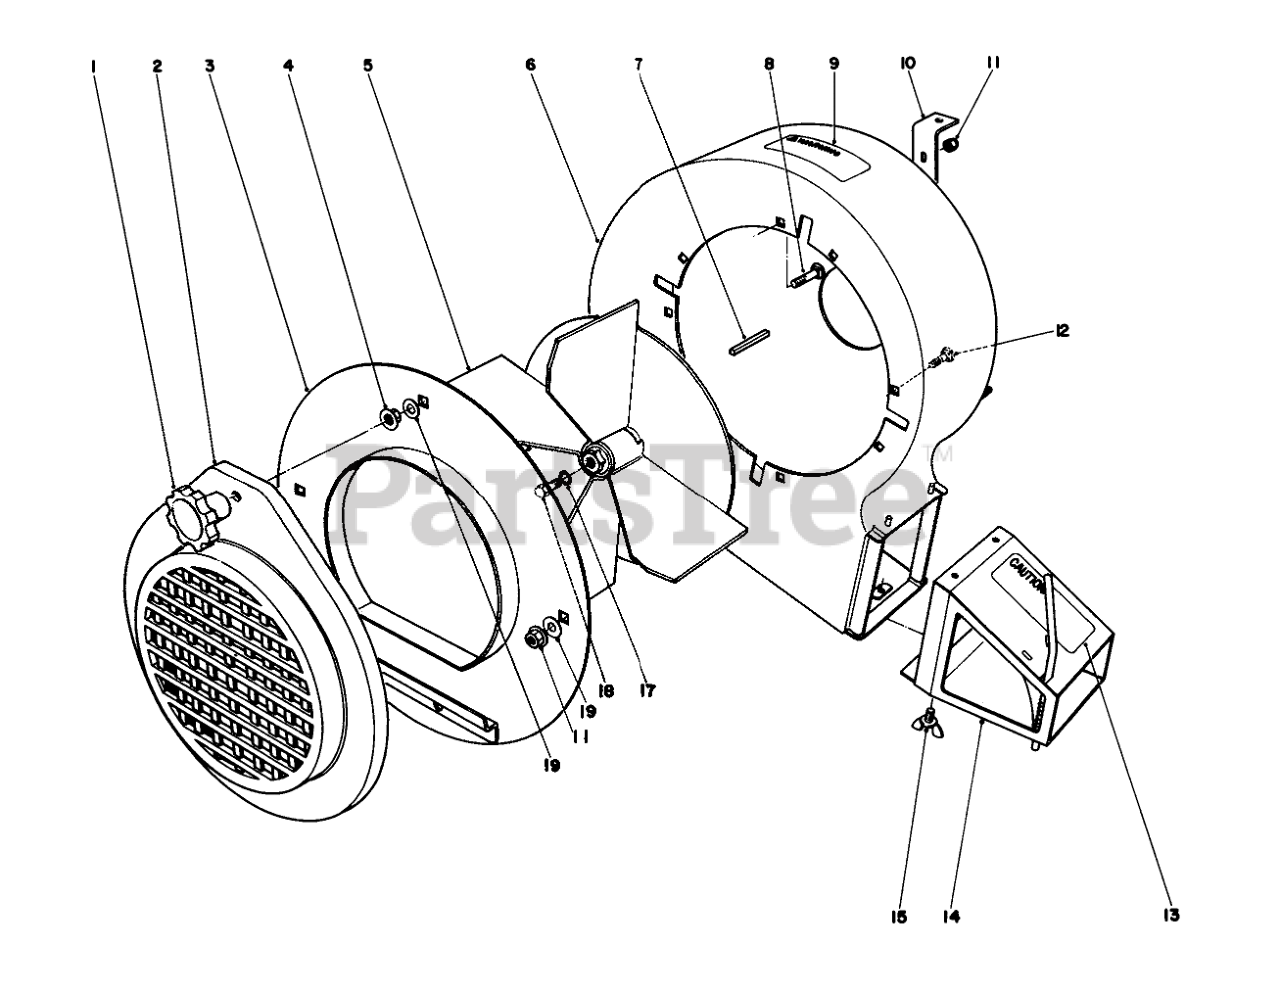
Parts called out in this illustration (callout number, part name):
2	INTAKE-BLOWER
3	Blower Cover
4	NUT-FLANGE
5	Fan
6	Blower Housing
7	KEY-SQUARE
8	SCREW-CARR
9	WARNING DECAL
10	Bracket-Housing
11	NUT-LOCK, CONE
12	SCREW-CARR
13	EXHAUST DECAL
14	Blower, Exhaust (Incl. Ref. #13)
15	1/4 - 20 3/4 WING SCR
17	WASHER-LOCK
18	SPEC SCREW
19	WASHER-FLAT
